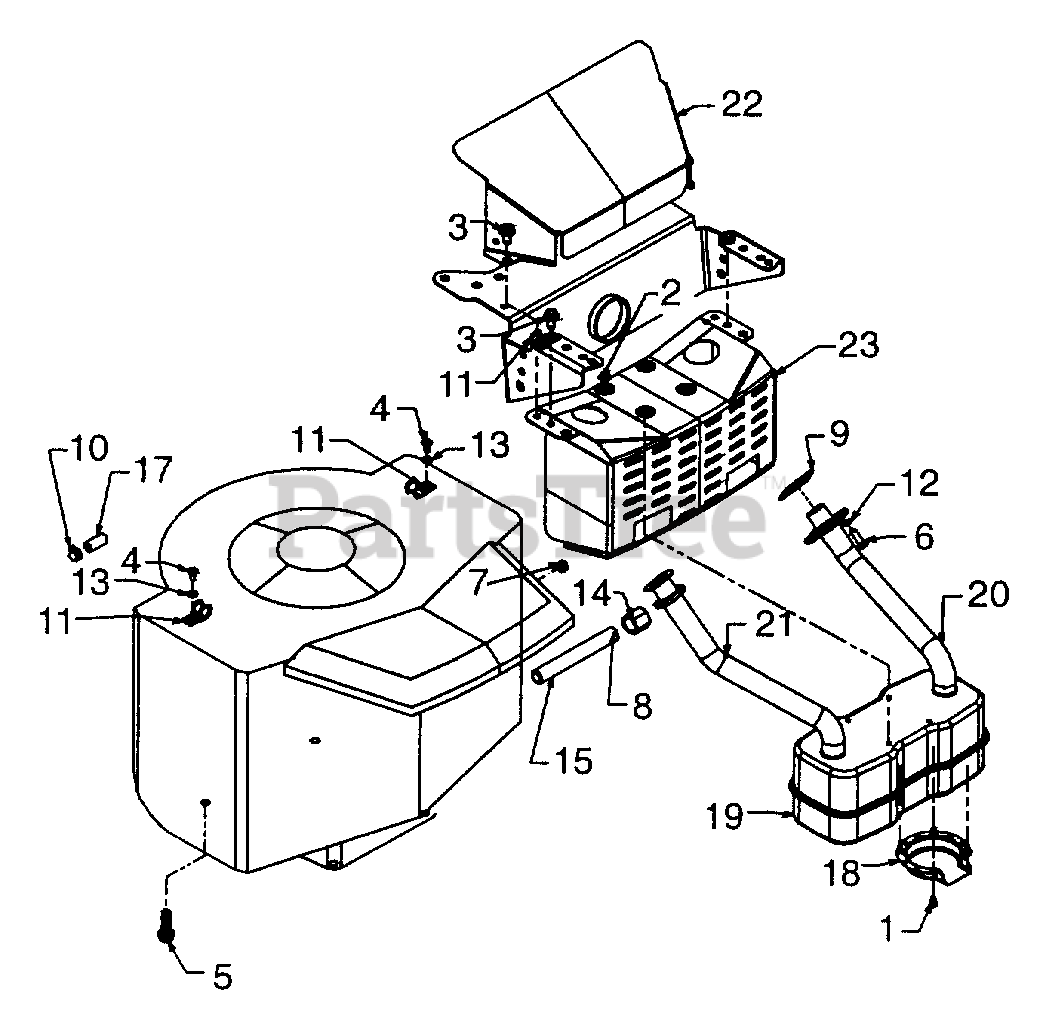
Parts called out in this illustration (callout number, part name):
1	Hex Tap Scr. #8-32 x .38" Lg.
2	Hex Wash. TT-Tap Scr. 1/4-20 x 5" Lg.
3	Hex Wash. TT-Tap Scr. 5/16-18 x .62" Lg.
4	Truss Mach. Scr. #10 x .5" Lg.
5	Hex Hd. Tap Scr. 3/8-16 x 1.25" Lg.
6	Hex Bolt 1/4-20 x .75" Lg.
7	Hex Sems Nut 1/4-20 Thd.
9	Exhaust Gasket
10	Hose Clamp
11	Clamp
12	L-Wash. 1/4" I.D.
13	Fl-Wash. .188" I.D. x .438" O.D.
14	Oil Drain Cap
15	Pipe Nipple 3/8 x 18 NPT
17	Fuel Line 26" Lg.
18	Deflector: Muffler
19	Muffler
20	Exhaust Pipe-L.H.
21	Exhaust Pipe-R.H.
